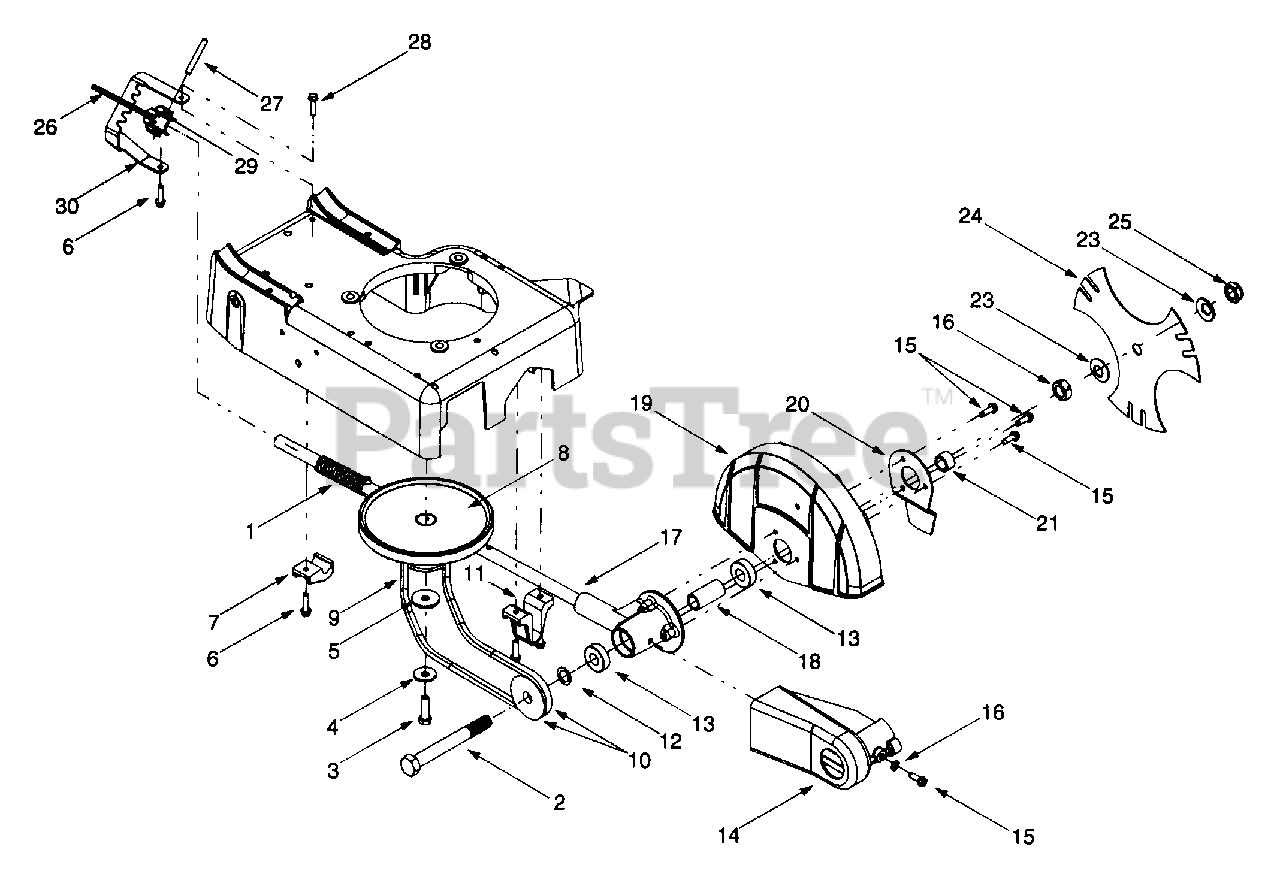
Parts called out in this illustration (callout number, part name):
1	Compression Spring
2	Hex Cap Screw, 5/8-18 x 5.25
3	Hex Cap Screw, 3/8-24 x 1.25
4	Bell Washer, .396 x 1.14 x.095
5	Flat Washer,.38 x 1.38 x .12
6	Hi-Lo Tap Screw, 1/4-15 x 1.0
7	Rear Rod Holder
8	Flywheel/Pulley Combination
9	V-belt
10	Sheave, .6255 x .6295
11	Front Rod Holder
12	Flat Washer, .635 x .93 x .06
13	Ball Bearing, .62 x 1.38 x.44
14	Belt Guard
15	Self-Tapping Screw,1/4-20x.75
16	Flat Washer, .281 x .50 x .063
17	Spindle Bearing Housing w/ Insert
18	Spacer, .628 x .875 x 1.818
19	Blade Guard
23	Bell Washer, .64 x 1.25 x .18
25	Nylon Lock Jam Nut, 5/8-18
26	Angle Adjustment Lever Ass'y
27	Spirol Pin, 1/4-20
28	Spirol Spring Pin, 1/4
29	Double Torsion Spring
30	Tilt Index Bracket
